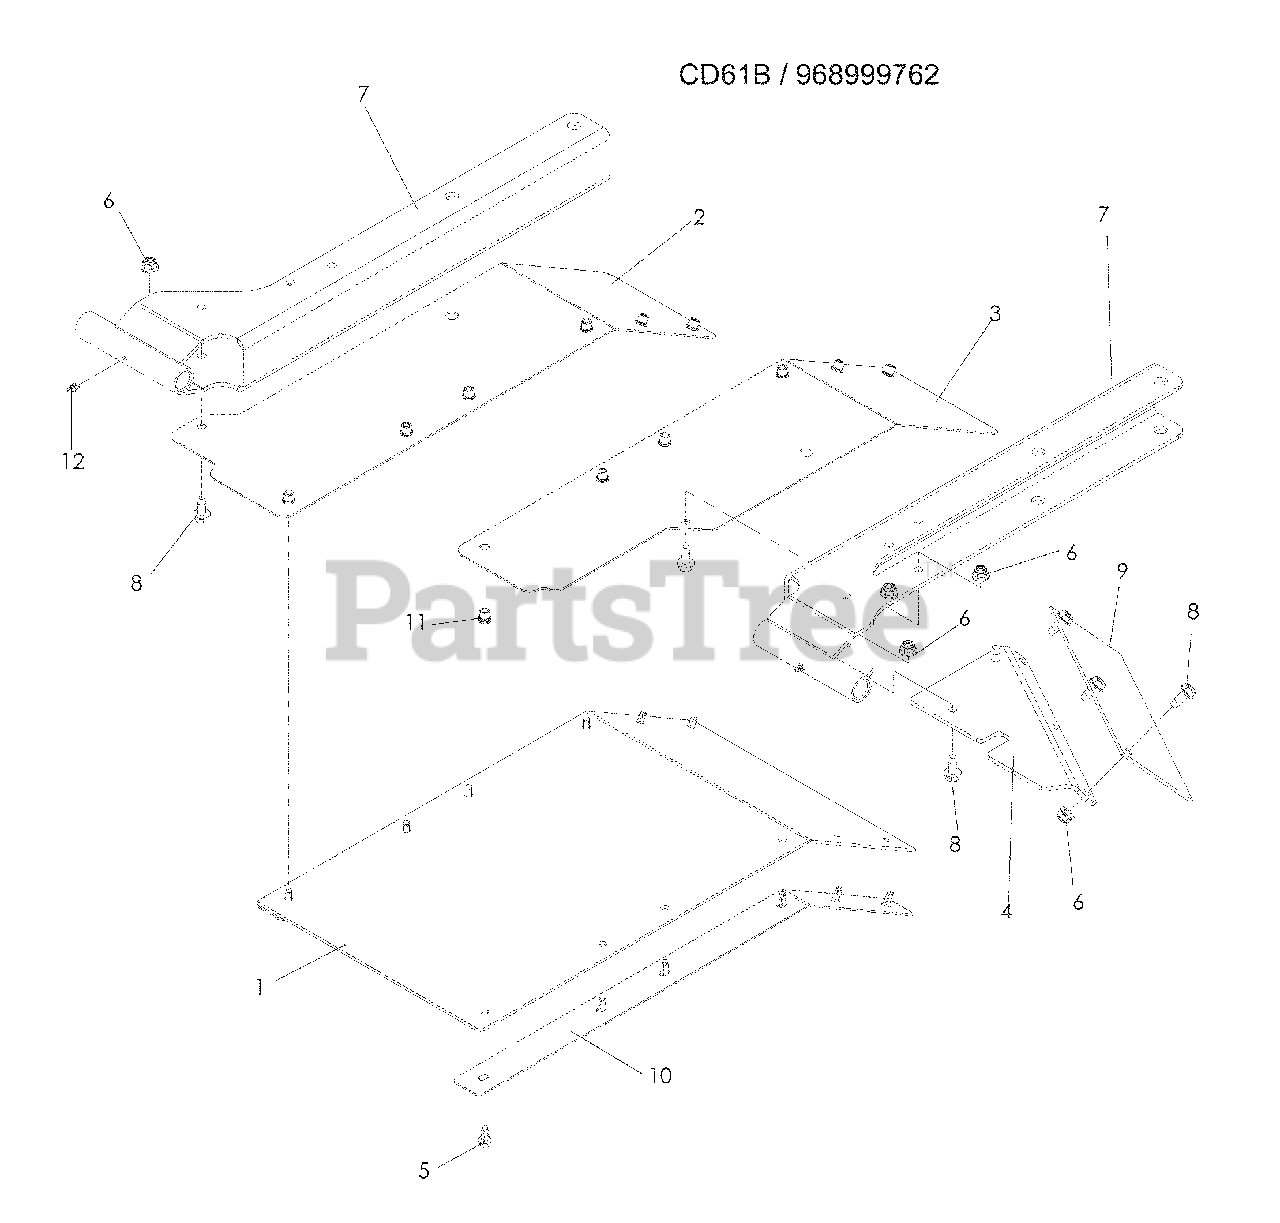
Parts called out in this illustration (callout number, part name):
1	GUARD, RUBBER
2	GUARD, DEBRIS, RIGHT
3	GUARD, LEFT, BZ
5	SCREW, ¼-20 x 5/8
6	NUT 5/16-18 NYLOC
7	STRUT, CMB, BZ
8	BOLT, 5/16-18 x ¾ THD FRM
9	GUARD, RUBBER, SMALL
10	STRAP, GUARD
11	KNURLED INSERT, ¼-20
12	ZERK
